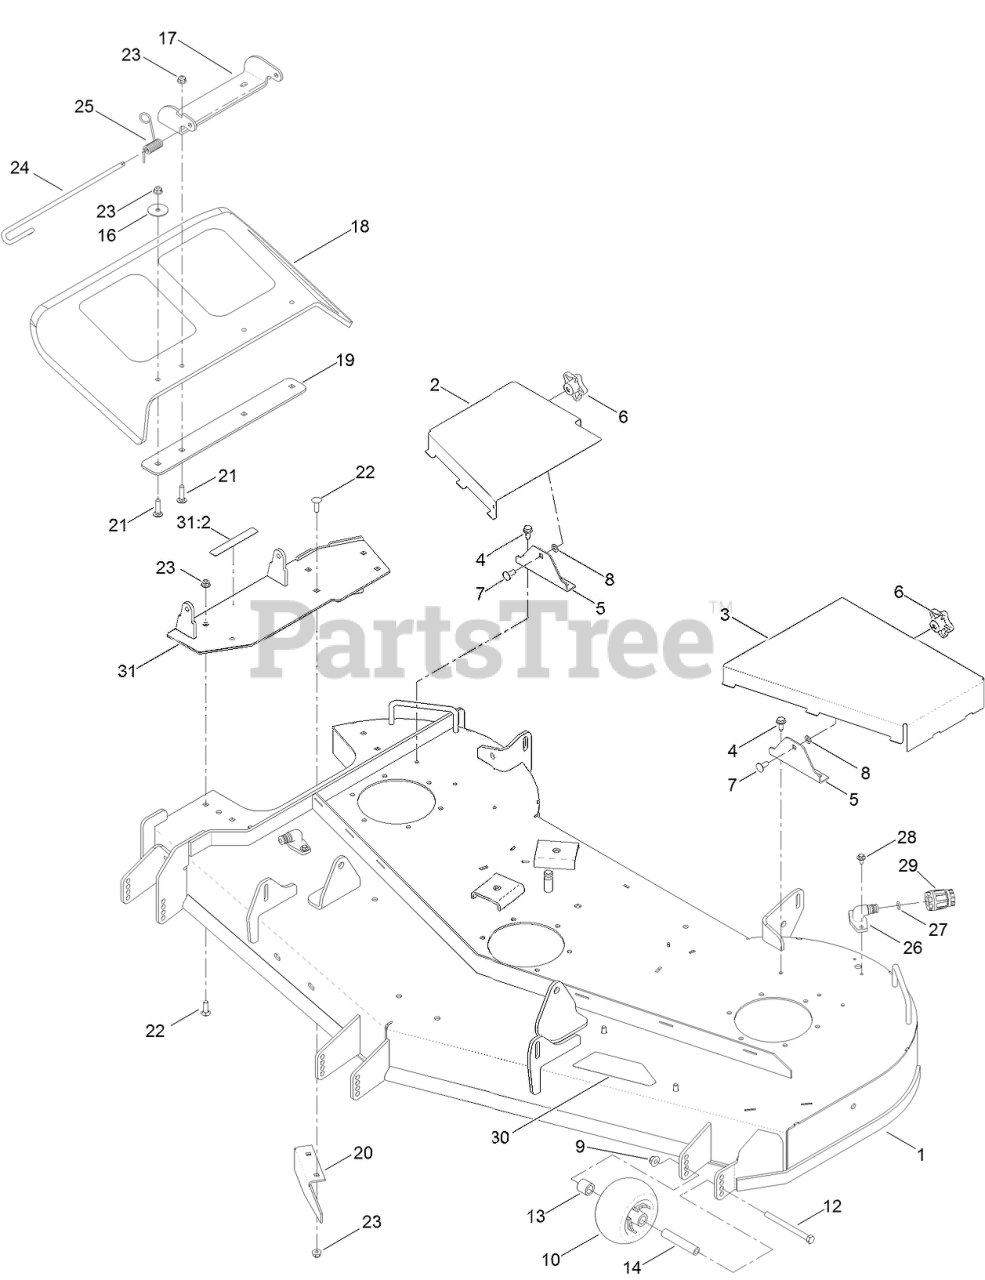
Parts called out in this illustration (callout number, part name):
1	60 INCH DECK ASM
2	COVER-BELT, RH
3	COVER-BELT, LH
4	SCREW-HWHTF
5	BRACKET-SUPPORT
6	KNOB-HANDLE
7	SCREW-CARR
8	RING-RETAINING, BOLT
9	NUT-HF, NI
10	ROLLER-SCALP, ANTI
12	SCREW-HH
13	SPACER-AXLE, REAR
14	TUBE-SPANNER
16	WASHER-FLAT
17	BRACKET-DEFLECTOR, UPPER
18	DEFLECTOR
19	PLATE-DEFLECTOR
20	BAFFLE-CUTOFF
21	SCREW-CARR
22	SCREW-CARR
23	NUT-HF, NI
24	PIN-CHUTE
25	SPRING-TORSION
26	FITTING-WASHOUT
27	O-RING
28	SCREW-HHFTF
29	CONNECTOR-HOSE
31	PIVOT-DEFLECTOR
31:2	DECAL-DANGER
